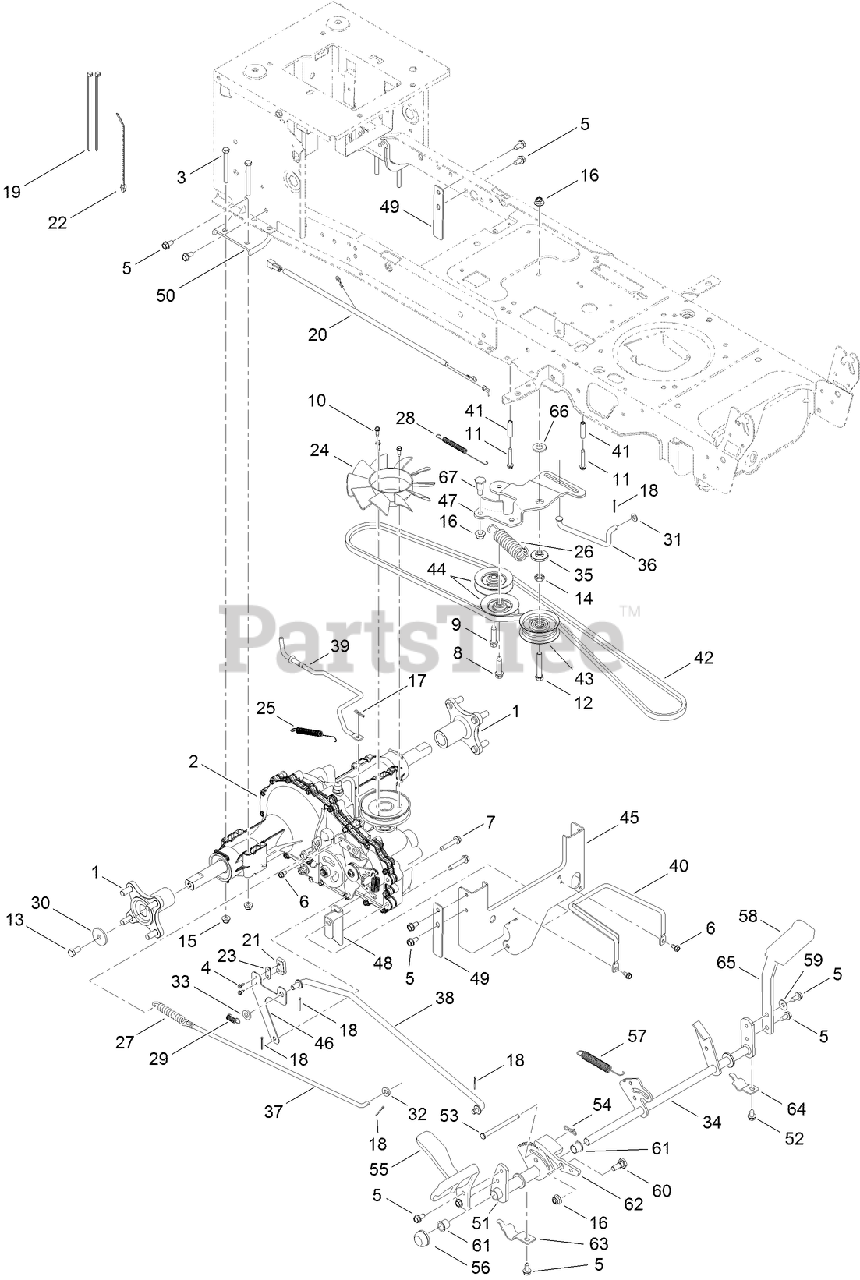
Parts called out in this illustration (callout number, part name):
1	WHEEL HUB ASM
2	TRANSMISSON
3	SCREW-HH
4	SCREW-HWHTF
5	SCREW-TAP
6	SCREW-HWHTF
7	SCREW-TAPTITE
8	SCREW-TAP
9	SCREW-TAP
11	SCREW-TAP
12	SCREW-HH
13	SCREW-HH
14	NUT-JAM
15	NUT-LOCK, FLANGE
16	NUT-LOCK, FLANGE
17	PIN-COTTER
18	PIN-COTTER
19	TIE-CABLE
20	HARNESS-JUMPER
21	SWITCH-SPRING, SHORT
22	TIE-CABLE
23	PLATE-INSULATOR
24	FAN-BLADE
25	SPRING-EXTENSION
26	SPRING-EXTENSION
27	SPRING-EXTENSION
28	SPRING-EXTENSION
29	SPRING-EXTENSION
30	WASHER-FLAT
31	WASHER-FLAT
32	WASHER-FLAT
33	WASHER-FLAT
34	BRAKE CONTROL ASM
35	SPACER-SHOULDER
36	ROD-BYPASS, FOOT PEDAL
37	ROD-BRAKE
38	ROD-CONTROL
39	ROD-DISENGAGE
40	KEEPER-BELT
41	SPACER
42	BELT-V
43	PULLEY-IDLER, FLAT
44	PULLEY-IDLER, Y TYPE
45	BRACKET-TORQUE
46	BRACKET-ACTUATOR, SWITCH
47	BRACKET-IDLER, CENTER DOUBLE
48	BRACKET-DECK
49	BRACKET-PLATE
50	BRACKET-AXLE
51	BRACKET-PEDAL, HYDRO
52	SCREW-HWH
53	PIN-CLEVIS
54	PIN-COTTER
55	PEDAL-CONTROL
56	CAP-PUSH
57	SPRING-EXTENSION
58	PAD-PEDAL, BRAKE
59	WASHER-BELL
60	BOLT-SHOULDER
61	BEARING-FLANGE
62	LATCH-CRUISE
63	BRACKET-STRAP, PEDAL SUPPORT
64	BRACKET-STRAP, PEDAL SUPPORT
65	BRACKET-PEDAL, BRAKE
66	WASHER-FLAT
67	SCREW-SHOULDER
